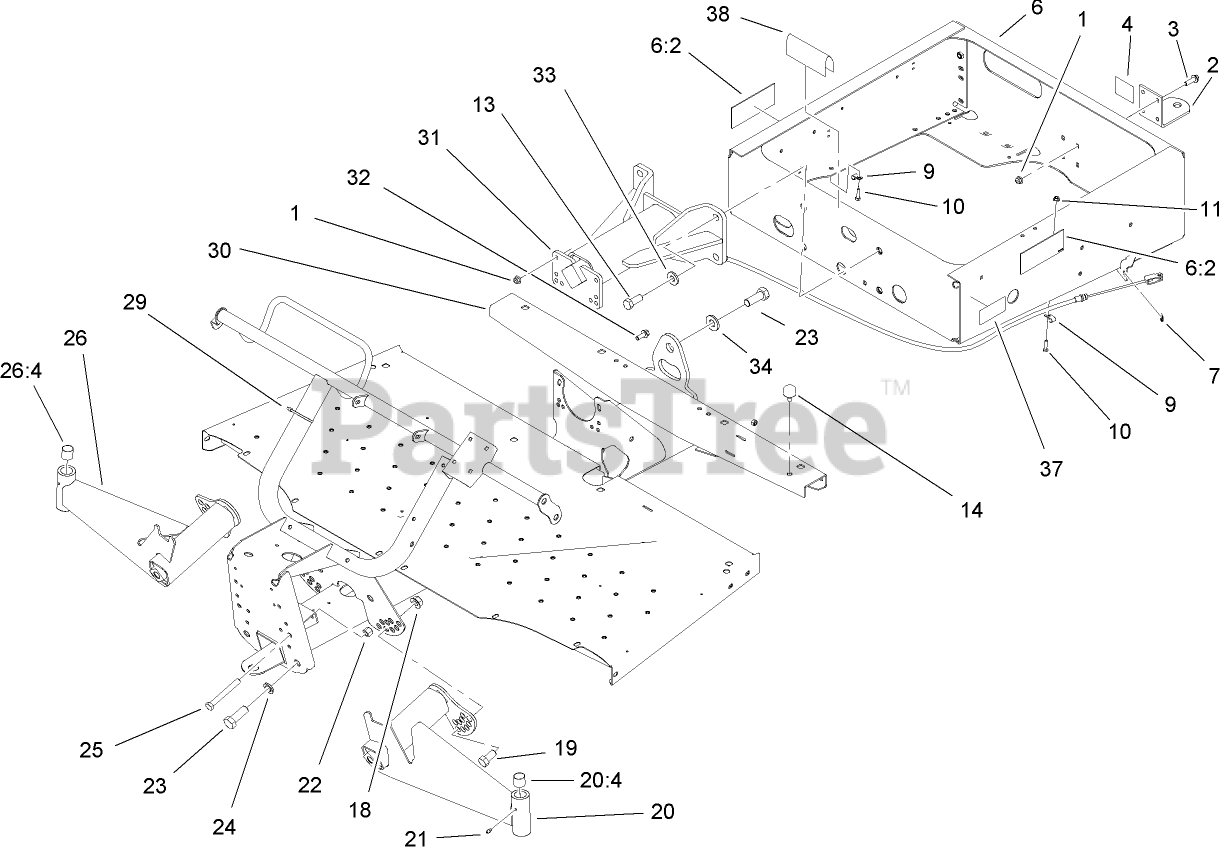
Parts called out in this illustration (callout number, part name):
1	NUT-HF, NI
2	HITCH-DUTY, LIGHT
3	SCREW-HHF
4	DECAL-RATING, HITCH (LIGHT DUTY)
6	REAR FRAME ASM
6:2	DECAL-WARNING
7	RING-RETAINING, EXTERNAL
9	CLAMP-R
10	SCREW-HH
11	NUT-HF
13	SCREW-HH
14	BUMPER-RUBBER
18	NUT-HF
19	SCREW-HH
21	FITTING-GREASE
22	NUT-LOCK, NI
23	SCREW-HH
24	WASHER-LOCK, INT
25	SCREW-HH
26	RH A-ARM ASM
29	TIE-CABLE
31	YOKE-PIVOT
32	SCREW-HHF
33	WASHER-FLAT
34	WASHER-HARDENED
37	DECAL-CAPACITY (CE)
